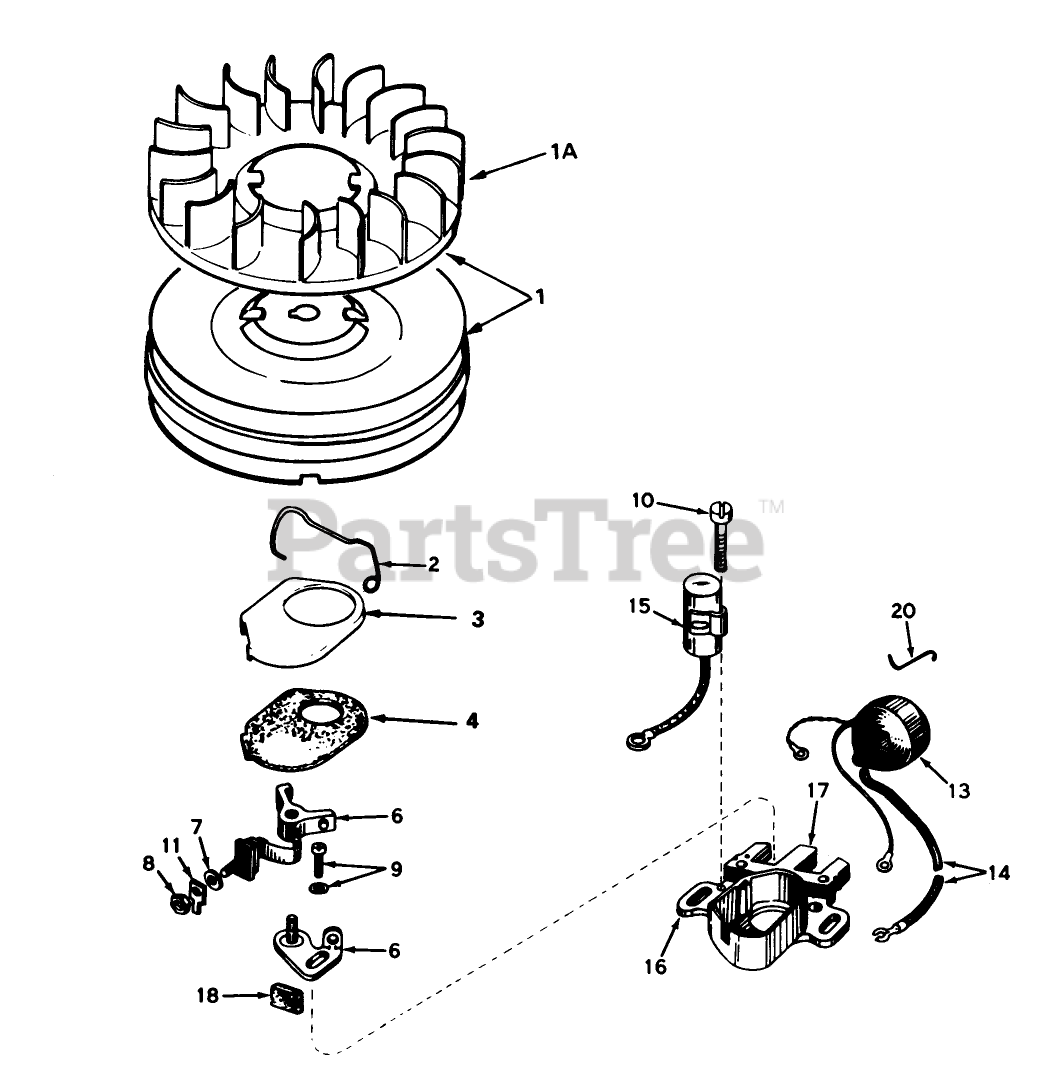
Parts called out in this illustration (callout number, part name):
1	Flywheel (Incl. No. 1A)
2	Spring Breaker Box
3	Cover-Dust
4	Gasket, Dust Cover
6	Breaker Assy.
7	Washer
8	DECAL
9	Breaker Screw
10	Condenser Screw
11	Terminal, Ground
13	Coil Assy. (Incl. No. 12)
14	Wire, Lead
15	Condenser
16	Core Plate
17	Stator Assy. (Incl. Ref. #2 thru 11, 13, 14, 16, 17 19)
18	Felt,Cam Wiper
20	Clip, Coil
